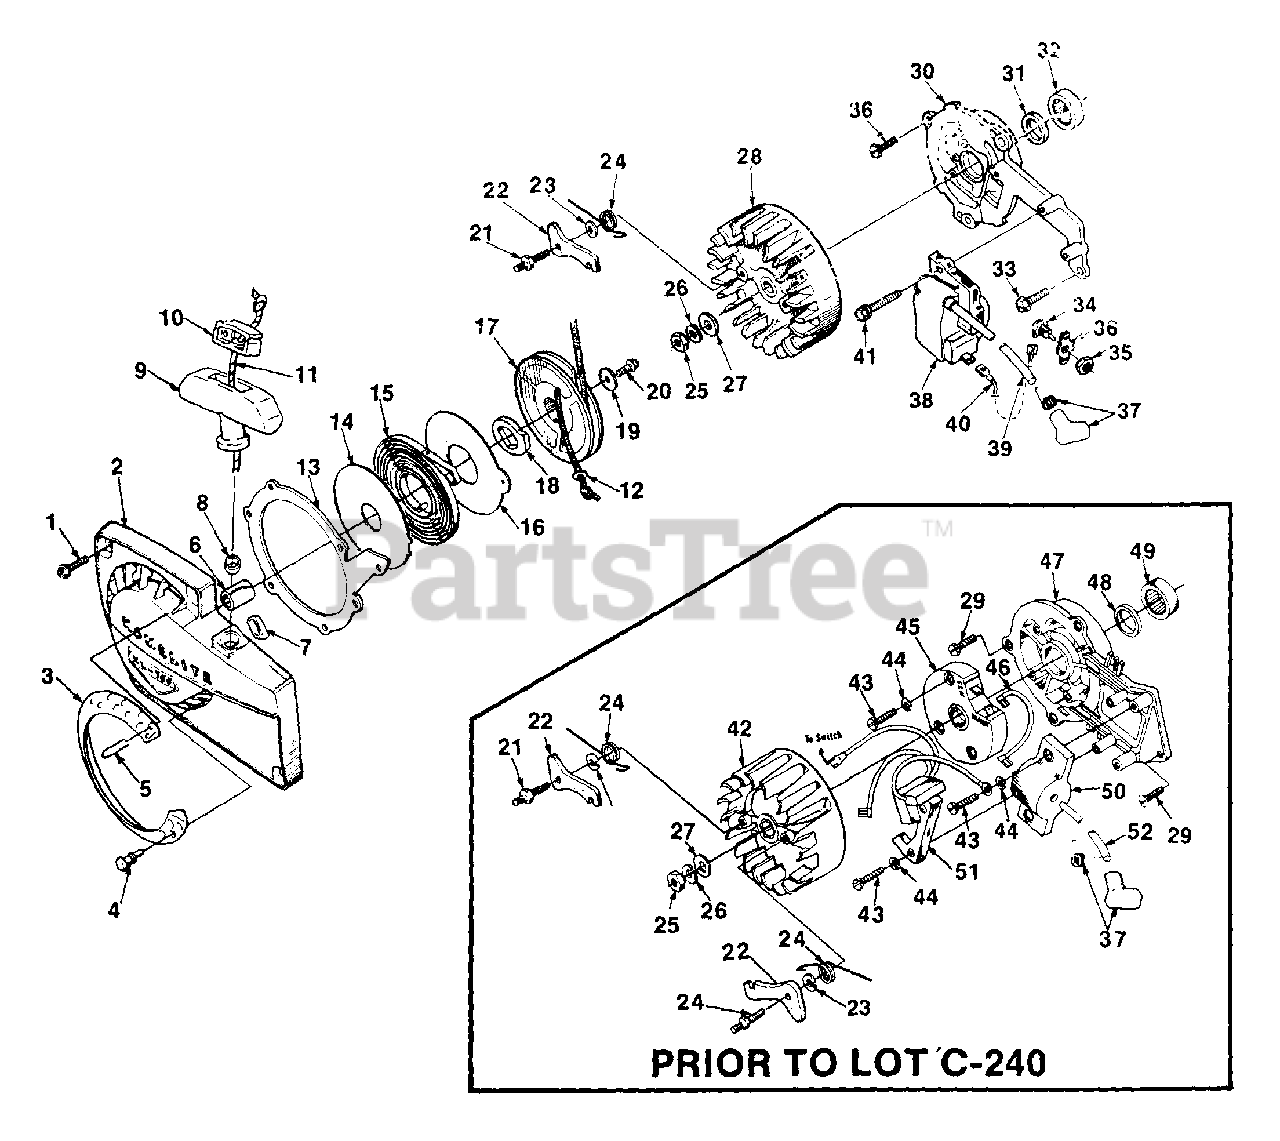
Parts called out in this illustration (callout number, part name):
1	SCREW-Hex hd. 12-24 x 5/8
2	HOUSING-Starter
3	KIT-Fan housing screen
4	STUD-Drive
5	FASTENER
6	BUSHING
7	BUSHING
8	BUSHING
9	GRIP-Starter
11	ROPE-Starter (48", #5)
13	RING-Air flow
17	PULLEY & CUP
18	LOCK-Spring
20	SCREW-Hex hd. 10-32 x 1/2
21	STUD-Starter pawl
22	STARTER PAWL
23	WASHER-Lock
24	SPRING
25	NUT-Hex 3/8-24
26	WASHER-Lock 3/8
27	WASHER-Flat 3/8
28	ROTOR-Magneto
29	SCREW-Hex 1/4-20 x 5/8
30	PLATE-Back
31	SEAL
32	BEARING
33	SCREW-Sems hex hd. 1/4-20 x 3/4
34	SWITCH
35	NUT
36	PLATE-Indicating
37	TERMINAL-Spark plug
38	MODULE-Ignition
39	LEAD-High tension
40	LEAD-Ground
41	SCREW-Sems hex hd. 8-32 x 1
42	ROTOR-Magneto
43	SCREW-Mach. hd. 8-32 x 3/4
44	WASHER
45	MODULE
46	LEAD-Transformer
47	PLATE-Back
48	SEAL
49	BEARING-Roller
50	COIL-Transformer
51	COIL & CORE
52	LEAD-High tension
